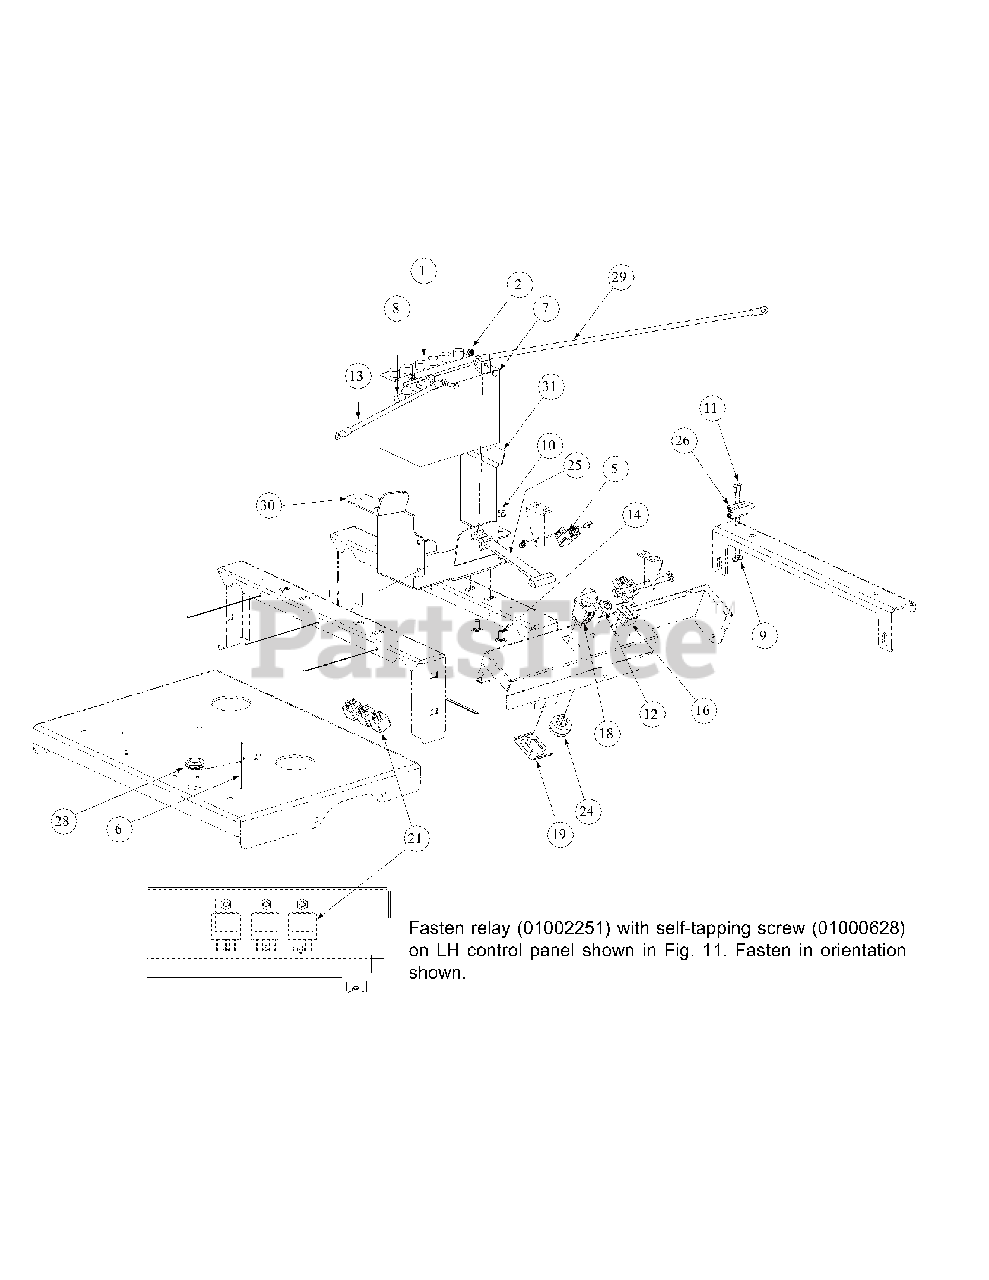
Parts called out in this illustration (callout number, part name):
1	Battery, 12V 225CCA 30 Min
2	Lock Nut, 1/4-20
5	Switch, Safety, NO/NC
6	Tie, Cable, 3/16 x .05 x 7.4"
7	Screw, Hex, Cap, 1/4-20 x .75
8	Boot, 1" OD Rubber Battery-PST, Red
9	Lock Nut, Nylon Insert, #10-32
10	Nut, Hex, Flange Lock, 3/8-16
11	Screw, Phillips Head, Machine, 10-32 x 5/8
12	Nut, W/Cap, 5/8-32 Ignition
13	Cable, Battery, Red, 36"
14	Carriage Bolt, 3/8-16 x .75 LG.
16	Meter, Hour
18	Switch, Electric, PTO
19	Bracket, PTO Switch Retainer
21	Relay, 12V 40A
24	Switch, Ignition, 6 Pin
24	Key, Ignition
25	Strap, Battery
26	Switch, Plunger, NO/NO
28	Grommet, .75 ID
29	Cable, Battery Red,28"
30	Mount Bracket, Battery
31	Mount Bracket, Battery
